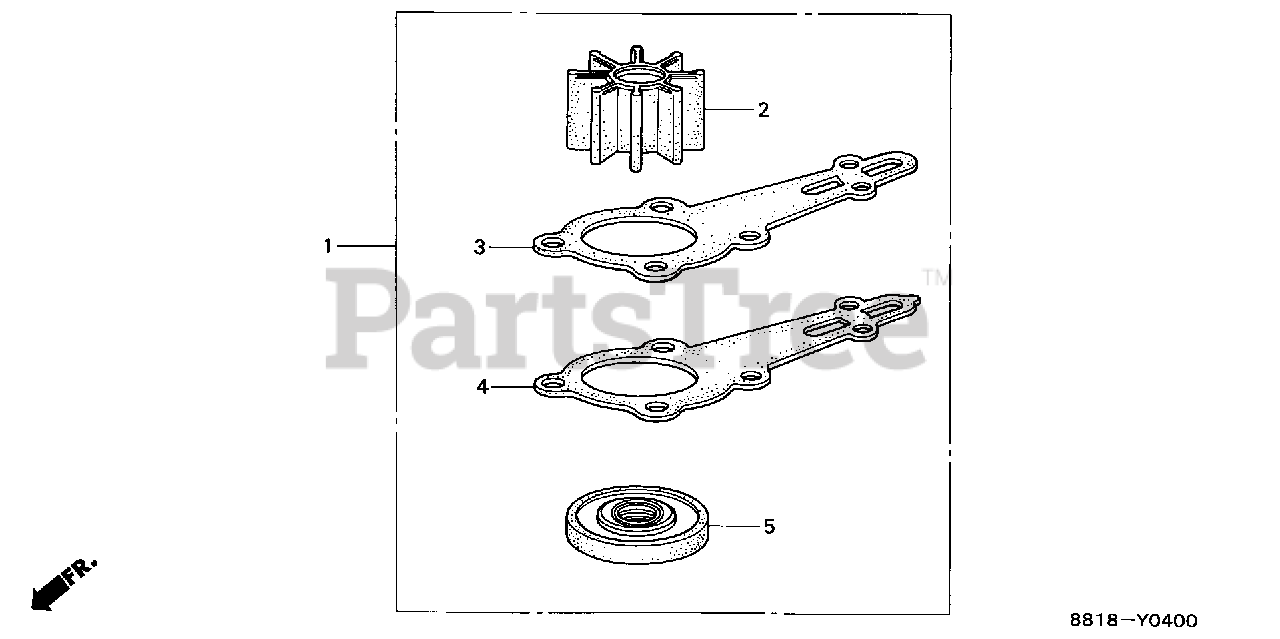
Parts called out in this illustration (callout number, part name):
1	IMPELLER KIT, WATER PUMP
2	IMPELLER, PUMP
3	GASKET A, IMPELLER
4	GASKET B, IMPELLER
5	SEAL, WATER (15MM) (NOK)
